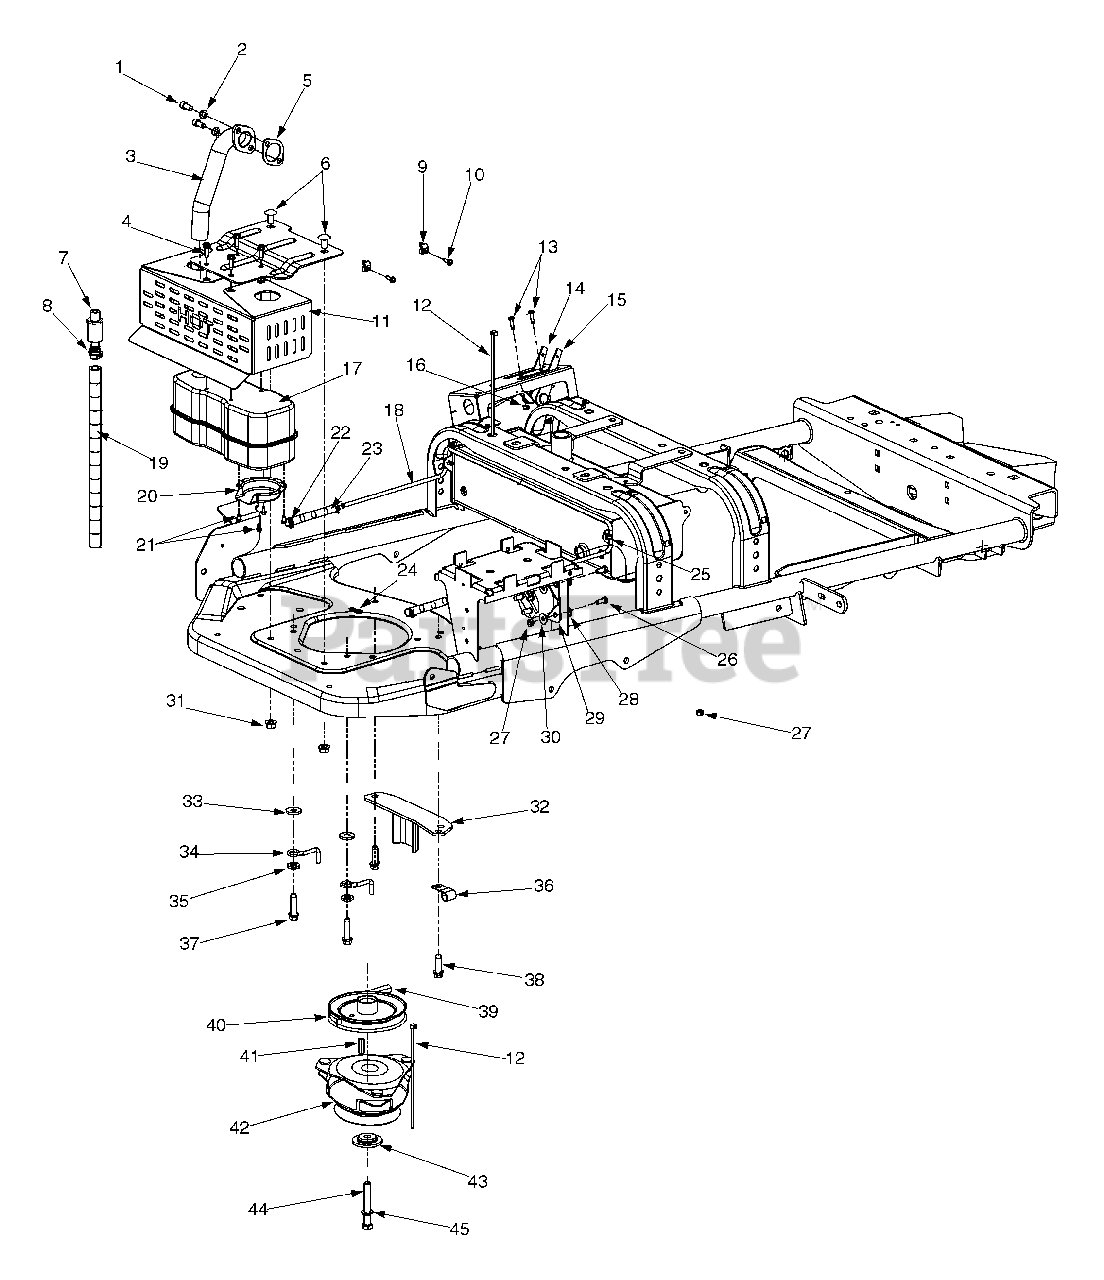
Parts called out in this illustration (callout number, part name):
1	Cap Screw 5/16-18
2	Lock Washer 5/16
3	Exhaust Pipe
4	Hex Washer Screw 1/4-20 x .75
5	Exhaust Gasket
6	Carriage Bolt 3/8-16 x .75
7	Oil Drain
8	Oil Drain Cap
9	Throttle Clamp
10	Hex Washer Screw #10-32 x .625
11	Muffler Bracket
12	Cable Tie
13	Screw #10-24 x .75
14	Throttle Cable Control 32"
15	Choke Cable Control 32.25"
16	Hex Lock Nut #10 - 24
17	Muffler
18	Fuel Line
19	Oil Drain Hose
20	Muffler Deflector
21	Hex Washer Screw #8-32 x .375
22	Hose Clamp
23	Fuel Line Hose
24	Lock Washer 5/16
25	Retainer Clip
26	Hex Cap Screw 1/4-20 x .620
27	Hex Lock Nut 1/4-20
28	Lock Washer 1/4 ID x 3/4 OD
29	Solenoid
30	Bell Washer .265 ID x .75 OD
31	Flange Lock Nut 3/8-16
34	Rear Belt Retainer Rod
35	Flat Washer .407 ID x .812 OD
36	Heat Shield Cable Clip
37	Hex Washer Screw 3/8-16 x 1.5
38	Hex Washer Screw 3/8-16 x 1.25
39	V-Belt
40	Pulley
42	Electric Clutch
43	Spacer Clutch
44	Hex Cap Screw 7/16-20 x 3.0
45	Lock Washer 7/16
